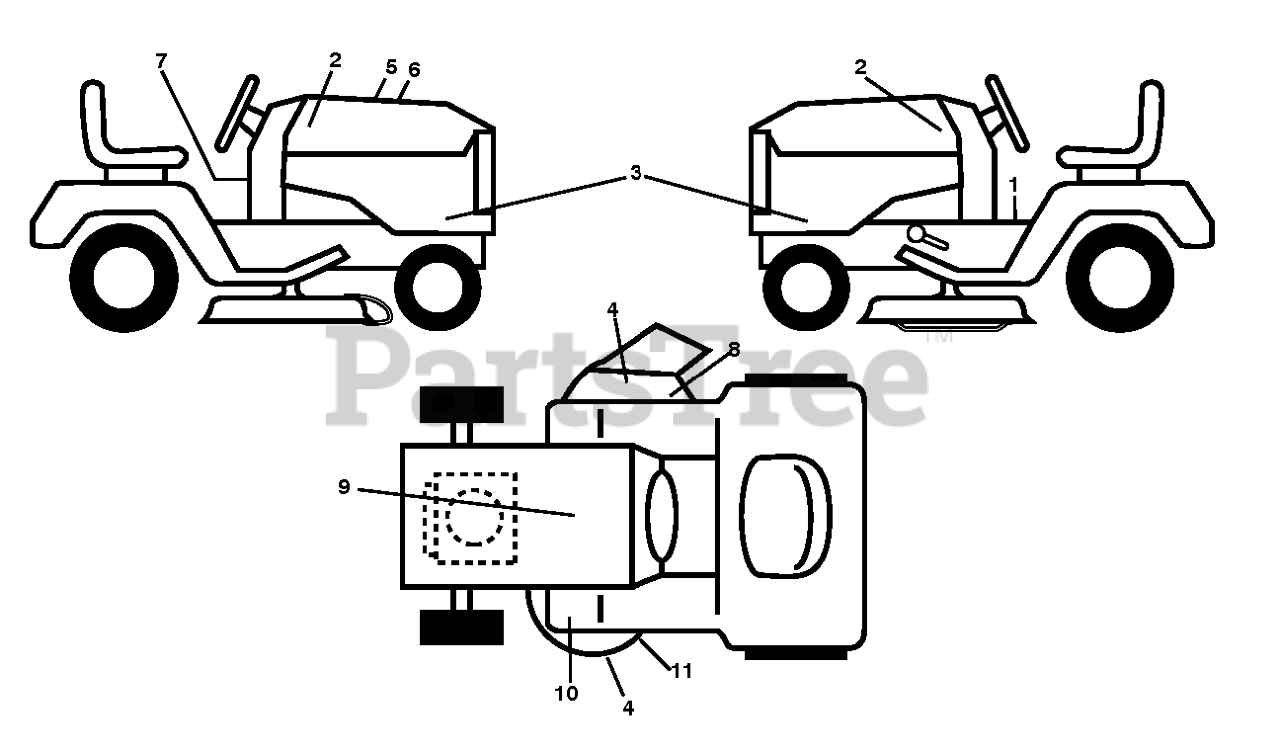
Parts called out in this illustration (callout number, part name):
1	DECAL.FENDER.WARNING.ENG
2	DECAL.BADGE.170MM.TEXTLOGO.
3	DECAL SDPL.HUSQGT2.YTHV42LS422
4	DECAL, NO STEP
5	DECAL.WARNING.CUST.RESP.E85.
8	DECAL, CAUTION
9	DECAL BTRY SYMBOLS
10	DECAL.PEDAL.HUSQ.CROWN
11	DECAL.MOWER.SCH.48/54
